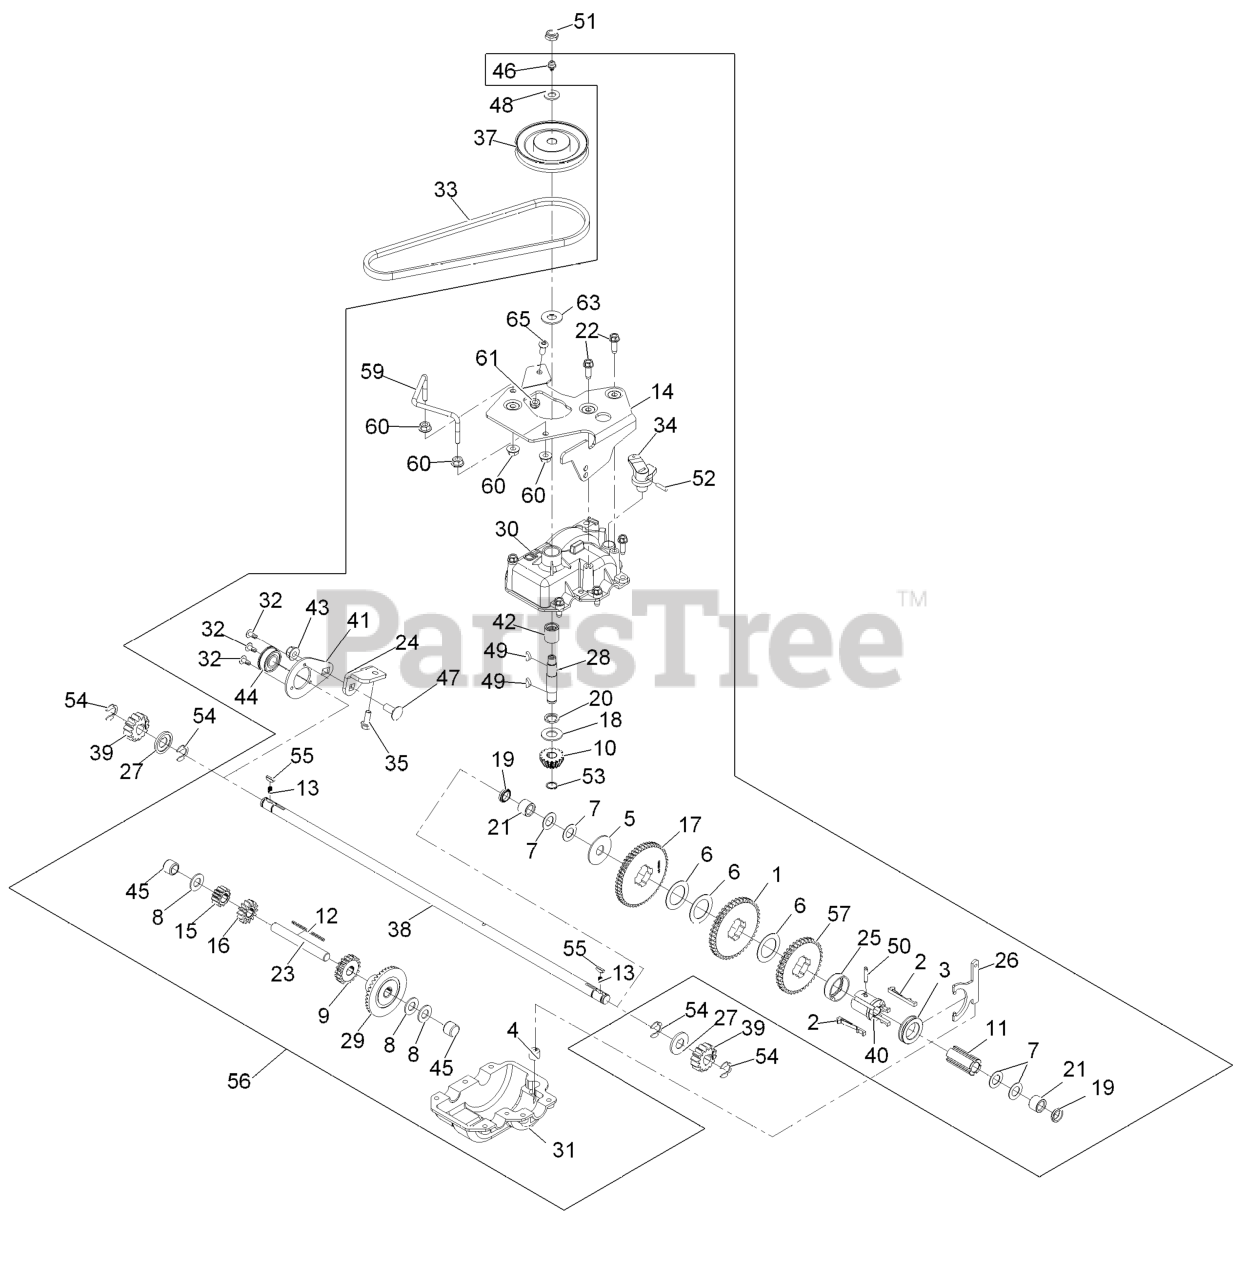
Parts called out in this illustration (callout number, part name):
1	GEAR-42T
2	KEY-SHIFT
3	COLLAR-SHIFT
4	BUSHING-YOKE
7	WASHER-PLAIN
8	WASHER-THRUST
9	GEAR-18T
10	PINION-BEVEL
13	SPRING-COMPRESSION
14	BRACKET-GUIDE, BELT
15	GEAR-12T
16	GEAR-14T
18	WASHER-THRUST
19	SEAL-OIL
21	BEARING-CAGED NEEDLE ROLL
22	SCREW-HWHTF
23	SHAFT-INTERMEDIATE
24	BRACKET-BEARING, PLATED
25	RETAINER-KEY
26	YOKE-SHIFT
27	WASHER-THRUST, OUTER
28	INPUT SHAFT ASM
29	GEAR-BEVEL
30	ASM,GEAR CASE W/BRG
31	GEARCASE-LOWER
32	SCREW-TAP
33	BELT-V, TRACTION
34	LEVER-SHIFT
35	SCREW-HWH
38	SHAFT-AXLE
39	GEAR-PINION
40	SLEEVE-4 DOG
41	PLATE-BEARING
42	BEARING-ROLLER, CAGED
43	NUT-HF, NI
44	BEARING-BALL
45	BEARING-NEEDLE, CLOSED
46	FITTING-GREASE, ZERK
47	SCREW-CARR
48	WASHER-FLAT
49	KEY-WOODRUFF
50	PIN-GROOVE
51	NUT-HEX
52	PIN-SPRING
53	RING-RETAINING
54	RING-RETAINING
56	ASM,GEARBOX (SERVICE ONLY
57	GEAR-38T
59	GUIDE-BELT
61	NUT-LOCK, NI
65	SCREW-HSBH
